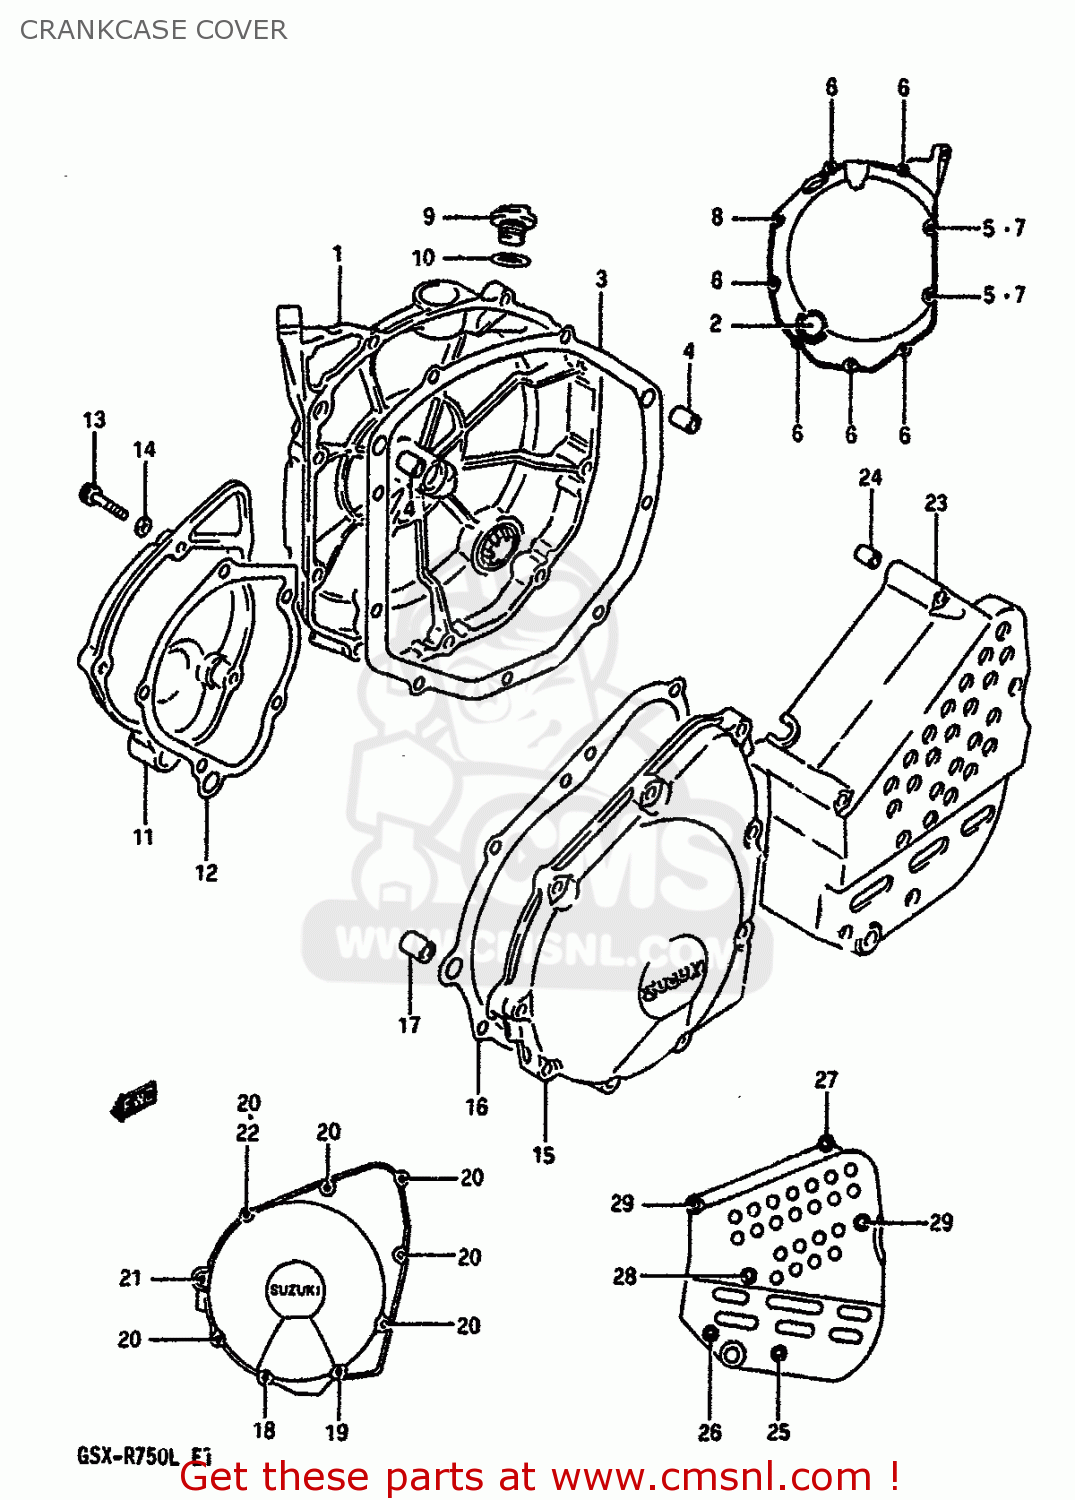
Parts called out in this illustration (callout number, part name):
1	COVER,CLUTCH
2	LENS,OIL LEVEL CHECK
3	GASKET,CLUTCH COVER (MCA)
4	PIN
5	GASKET(5.8X11X1.2) (NAS)
6	BOLT
7	BOLT
8	BOLT
9	PLUG
10	O RING(D:3.1,ID:16.8)
11	COVER,SIGNAL GENERATOR
12	GASKET,SIGNAL GENERATOR COVER
13	BOLT
14	GASKET(5.8X11X1.2) (NAS)
15	COVER,STARTER GEAR
16	GASKET,STARTER GEAR COVER (NA)
17	PIN (11X20)(SUS)
18	BOLT
19	BOLT
20	BOLT
21	BOLT
22	GASKET(5.8X11X1.2) (NAS)
23	COVER,SPROCKET
24	PIN
25	BOLT
26	BOLT
27	BOLT
28	BOLT
29	BOLT
